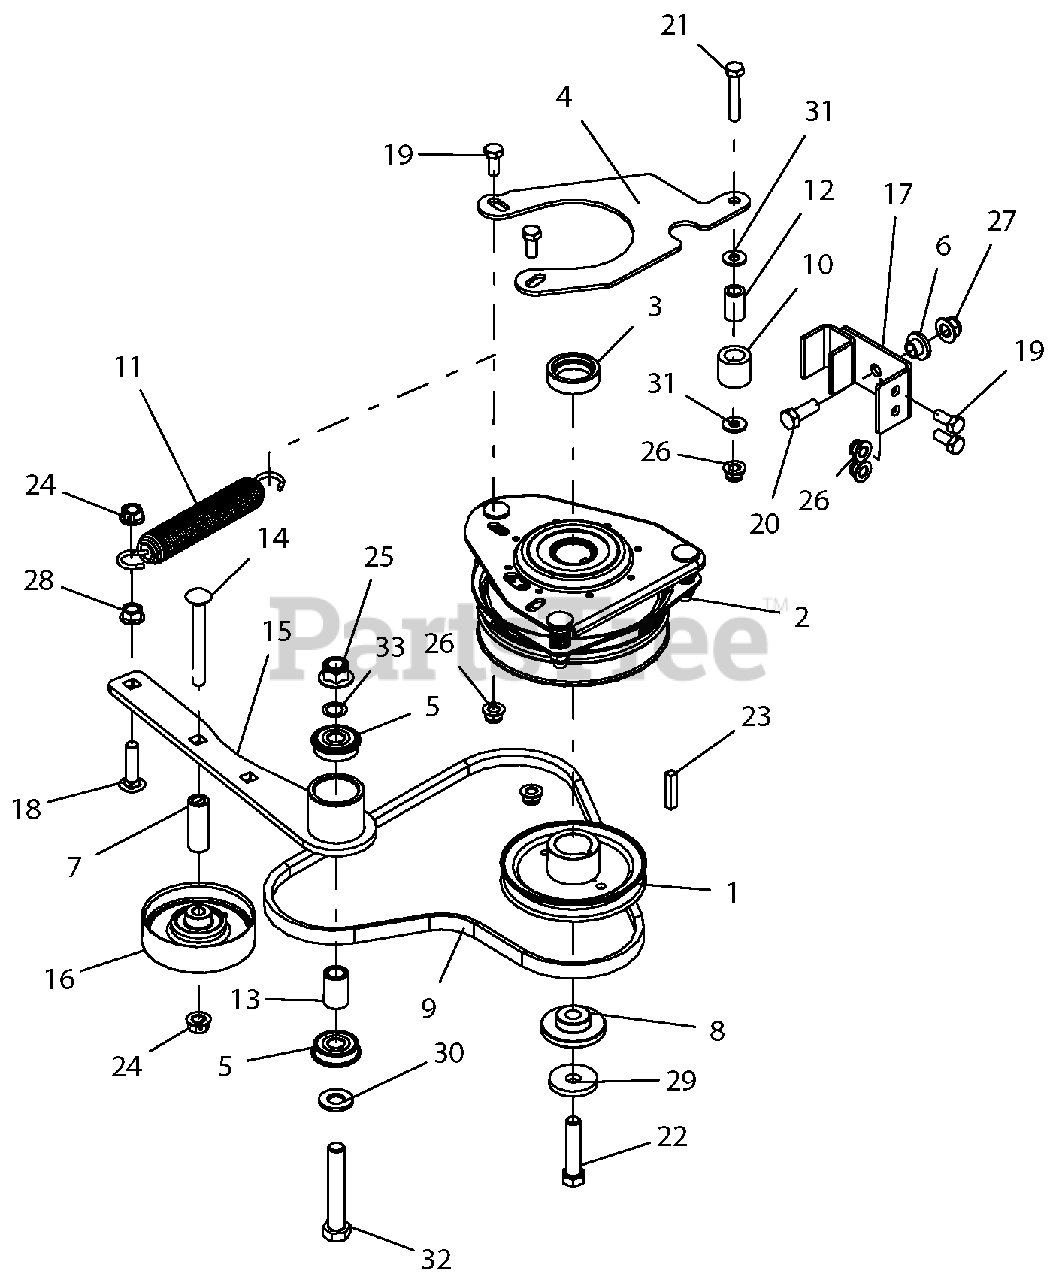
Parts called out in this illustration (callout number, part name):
1	SHEAVE, ENGINE 4.50 OD X 1.127
2	CLUTCH, ELEC OGURA GT1A-AR03
3	SPCR, CLUTCH
4	PLATE, CLUTCH DOG
5	BRG, BALL .501 X 1.38 X .438 SEALED
6	BSHG, FLG .385 X .500 X .875 X .406
7	BSHG, SLV .385 X .625 X 1.75
8	BSHG, -FLG .469 x 1.06 x .574 x 2.0
9	V-BELT, 4L RAW EDGE LAMINATED
10	BUMPER, RUBBER .62 X 1.0 X .88 LG
11	SPRG, EXTENSION
12	BUSH.,S.391X.622X.95 ST REV A
13	SPACER, .510 X .750 X 1.148
14	BLT-RDHDSQNK .38-16X3.25 G5 Y
15	WLDMT, HYDRO DRIVE IDLER ARM
16	IDLER, FLAT - 3.50" X .75"
17	WLDMT, CLUTCH STOP
18	BLT-RDHDSQNK .38-16X1.50 G5 Y
19	BLT-HEX .31-18X.75 GR5 YWZC
20	BLT-HEX .38-16X1.00 GR5 YWZC
21	BLT-HEX .31-18X1.75 GR5 YWZC
22	BLT-HEX .44-20X2.00 GR8 YWZC NYTORQ
23	KEY-SQ .250X.250X1.250
24	NUT, LK-CTR-FLG .38-16 YWZC
25	NUT-LK-NYL-FLG .50-13 YWZC
26	NUT-LK-NYL-FLG .31-18 YWZC
27	NUT-LK-NYL-FLG .38-16 YWZC
28	@NUT-SPNLK-FLG .375-16 YWZC
29	WSHR, 7/16" SPRING DISC
30	WSHR-FL-STL.531X1.06X.095YWZC
31	WSHR-FL-STL.312X.734X.065 YWZ
32	BLT-HEX .50-13X3.00 GR5 YWZC
33	WASHER-FLAT-STL, .500 X .750 X .020
